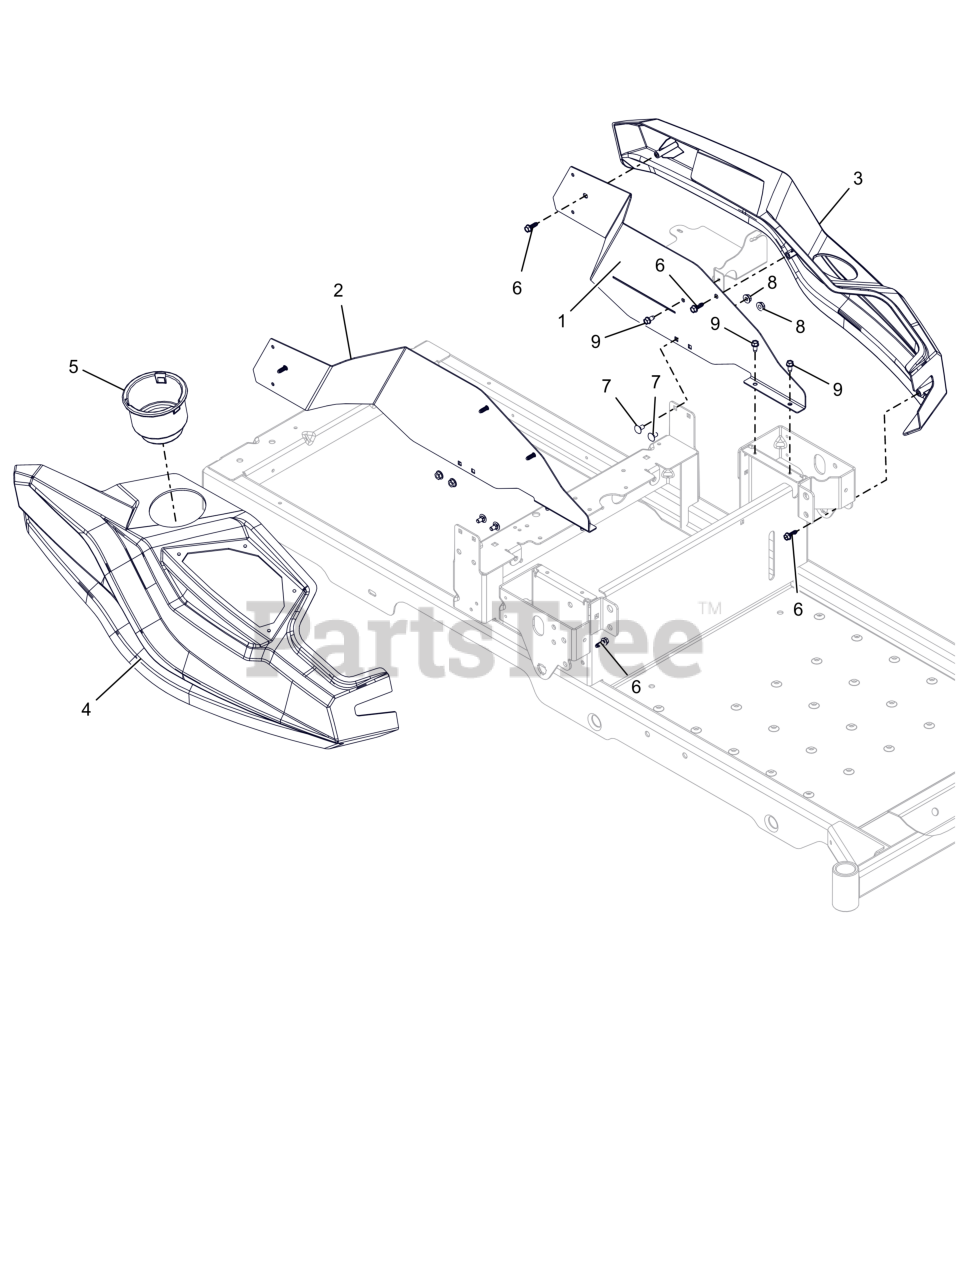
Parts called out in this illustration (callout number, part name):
1	BRKT, FENDER MOUNTING LH (ORANGE)
2	BRKT, FENDER MOUNTING RH (ORANGE)
3	KIT-FENDER WITH DECAL
4	FENDER, RH - ZOOM
5	CUPHOLDER, SNAP-IN 3.75OD
6	SCR, PLASTITE .25-10X.75 ZCC
7	BLT, RHSN .25-20X.500 G5 ZCC
8	NUT-LK-CTR-FLG .25-20 ZC120
9	SCR-TAP .25-20X.50 HWH ZCC
